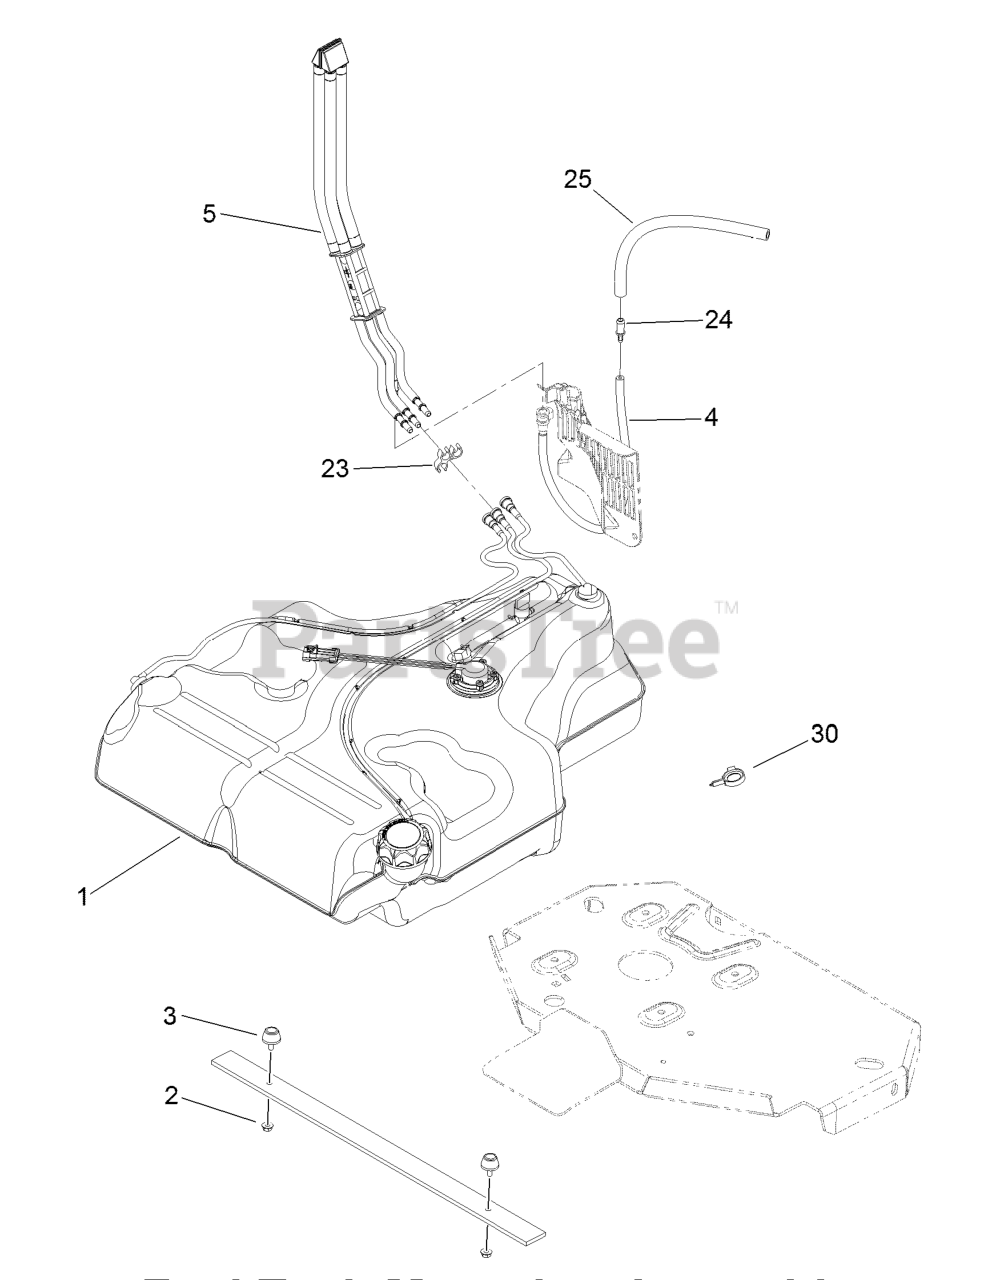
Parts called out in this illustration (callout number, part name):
3	BUMPER-RUBBER
4	HOSE ASM
5	FUEL MANIFOLD VENT ASM
23	CLIP-SPACER
24	FITTING-STRAIGHT
25	HOSE-FUEL
30	CLAMP-HOSE
